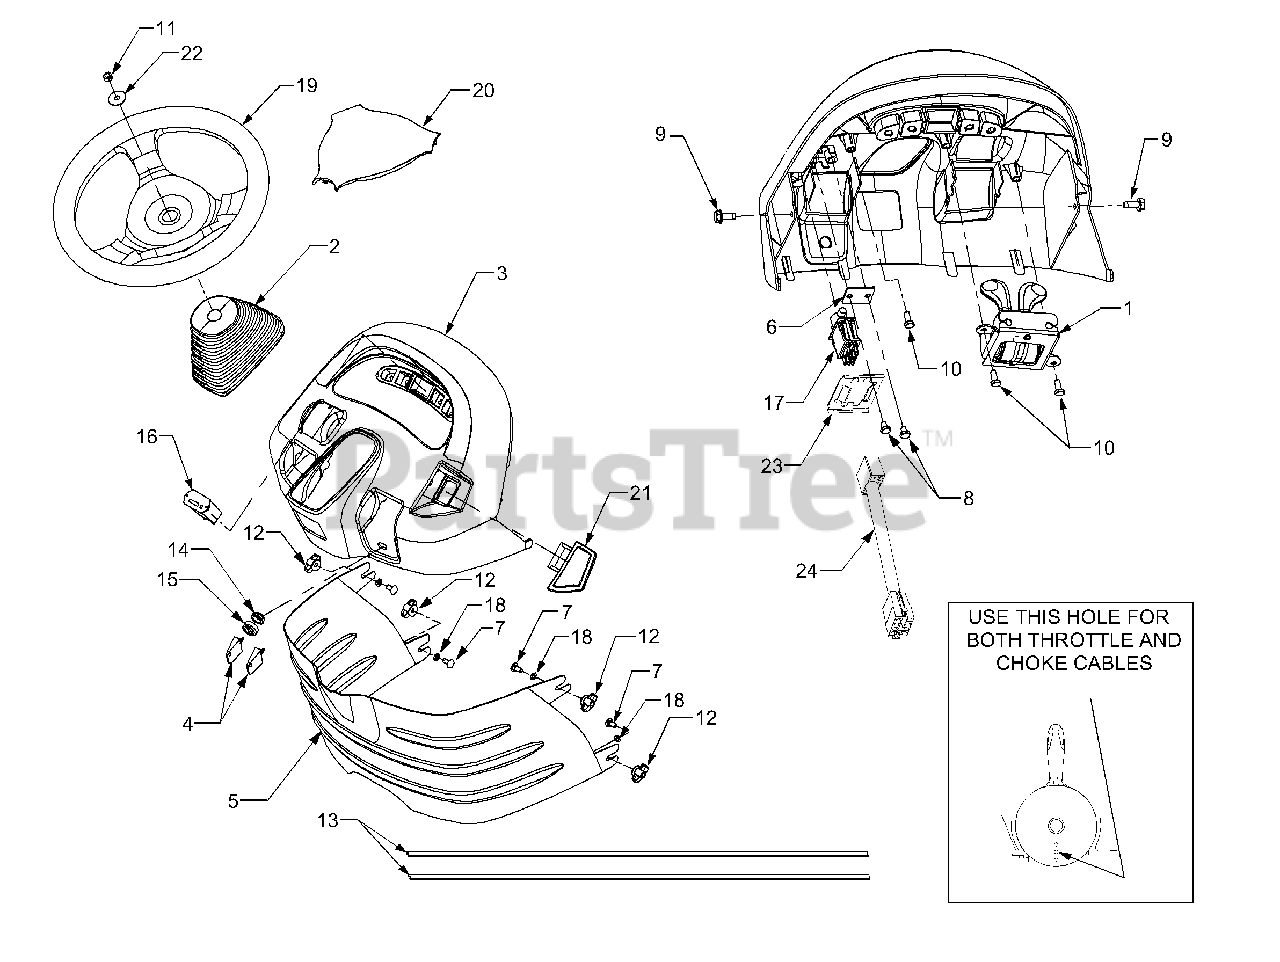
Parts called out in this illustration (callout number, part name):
1	Control Assembly, Throttle/Choke
2	Boot, Tilt Steer
3	Dash Panel
4	Key, Ignition (Set of 2)
7	Carriage Bolt, 1/4-20 x .62
8	Screw, Hex Cap 1/4-20 x .375 GR5
9	Screw, Hex Wash. Hd. Tapp 5/16-18 x .75
10	Screw, Hex Cap 1/4-20 x .50 GR5
11	Nut, Hex Lock, 5/16-24
12	Wing Nut, 1/4-20 w/Bell Washer
13	Seal, Screen
14	Nut, Ignition Switch, 5/8-32
15	Cap, Ignition Switch
16	Hour Meter
17	Switch, PTO
18	Nut, Push
19	Steering Wheel
20	Cover, Steering Wheel
21	Handle, PTO Switch
22	Washer, Flat, .34 x 1.5 x .10
23	Bracket, PTO Switch Retainer
24	Harness, PTO Adapter w/Diode
